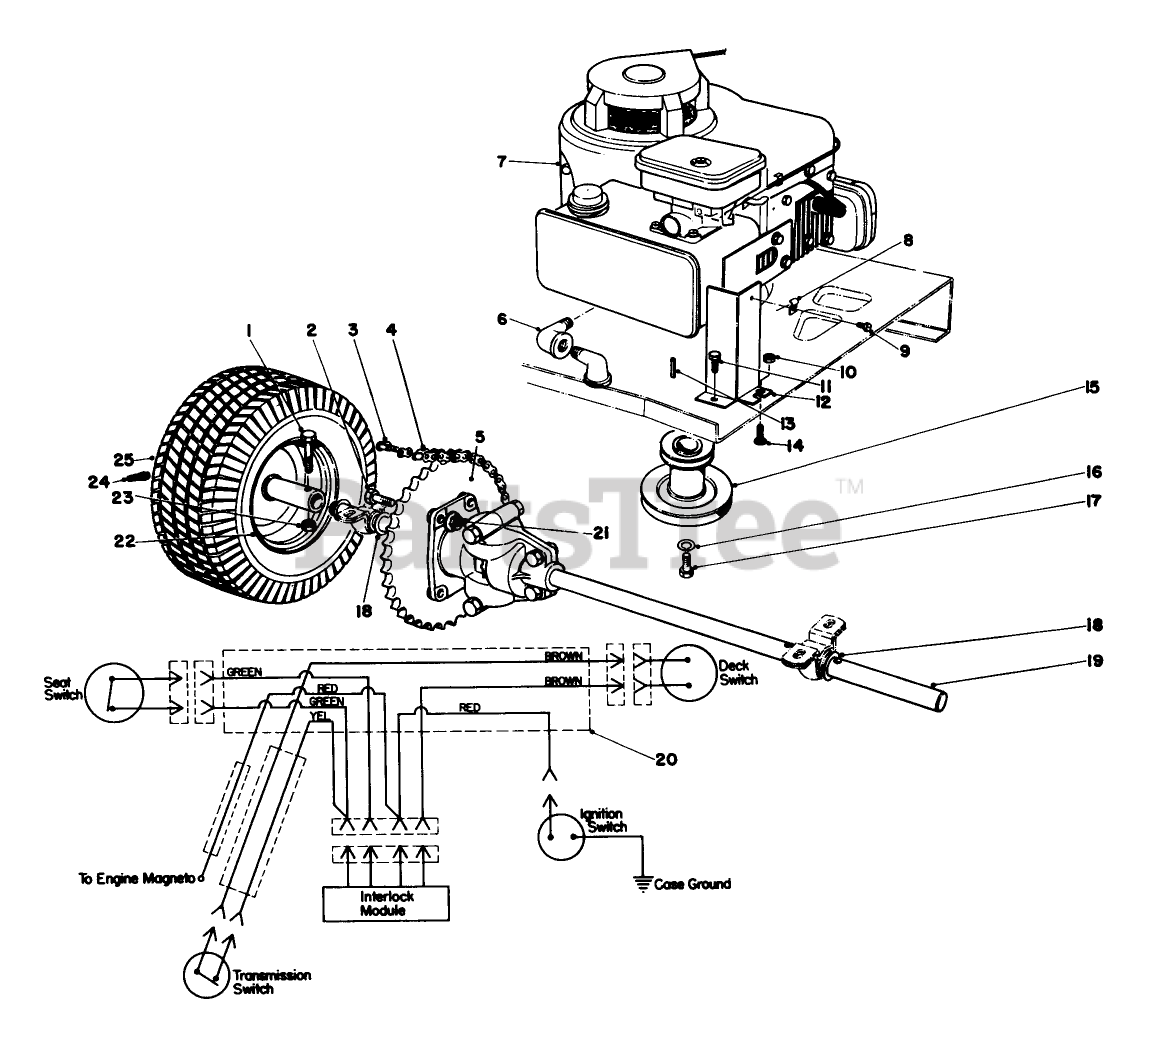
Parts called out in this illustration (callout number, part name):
1	SCREW-HH
2	SCREW-HH
3	LINK-CONNECTING
4	ROLLER CHAIN
5	Sprocket
6	90deg. Street Elbow
7	Engine
9	Screw
10	NUT-KEPS
11	SCREW-HWHTF
12	Support-Wire
14	5/16-18X5/8 TRS HD MS
15	ENGINE SHEAVE
16	WASHER-LOCK
17	SCREW-HH
18	WASHER
19	Differential
20	Wiring Harness
21	NUT-LOCK, CONE
23	NUT-LOCK, CONE
24	STEM-VALVE
25	Tire
